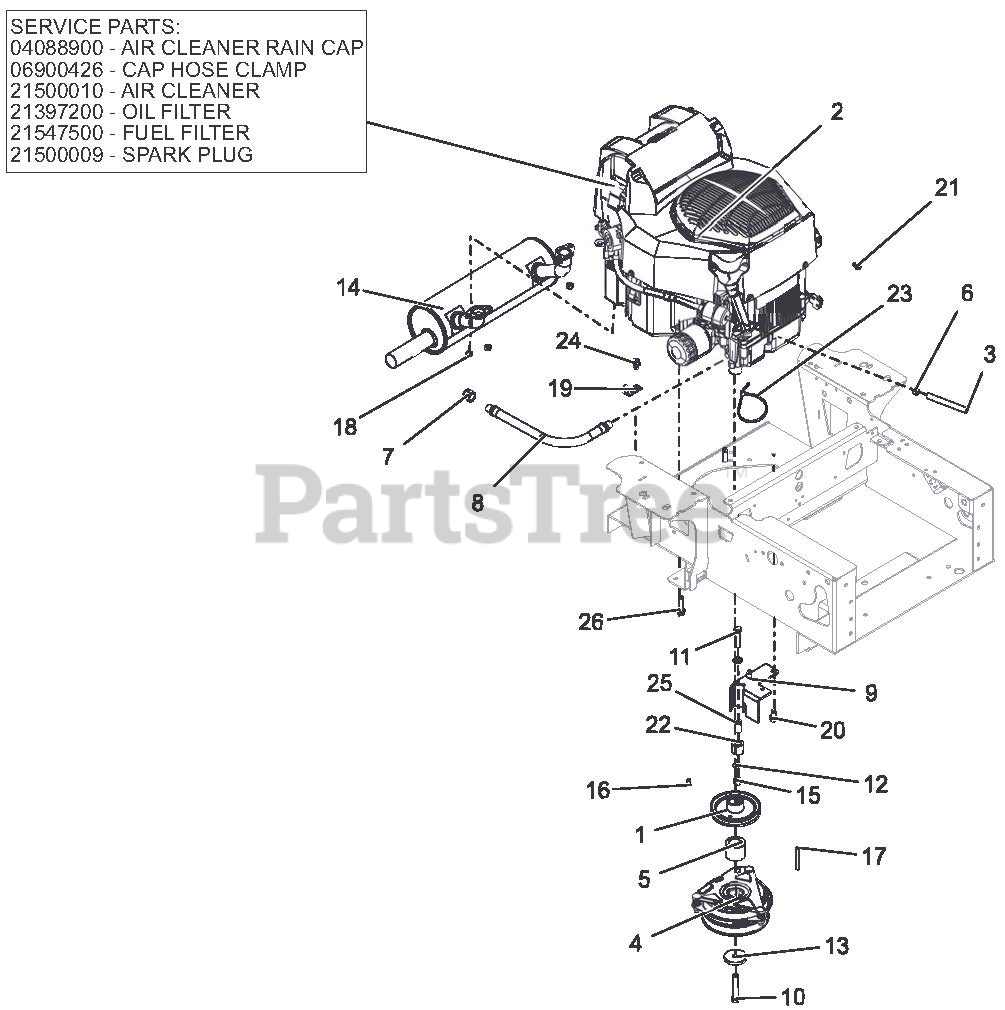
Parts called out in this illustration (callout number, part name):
1	PULLEY, 4.50 OD X 1.127 ENGINE - BLACK
2	ENGINE, KOHLER ZT730 CONFIDANT
2	AIR CLEANER RAIN CAP
2	CAP HOSE CLAMP
2	AIR CLEANER
2	OIL FILTER
2	FUEL FILTER
2	SPARK PLUG
3	.25 LOW-PERM GAS HOSE 7.50" VALVE TO ENGINE
4	CLUTCH, OGURA GT2.5-FE02
5	SPCR, 1.125 X 1.75 X 1.400
6	CLAMP, FUEL LINE
7	PIPE, CAP 3/8 NPT FEMALE
8	HOSE, HYD .38-11-OK M6N0-M6N0
9	BRKT, CLUTCH STOP
10	BLT-HEX .44-20 X 2.50 GR5 EP 80 YWZC
11	BLT-HEX .38-16 X 1.75 GR5 YWZC
12	WSHR-FL-STL .406 X .812 X .065 YWZ
13	WSHR-FL-STL .469 X 2.00 X .25 YWZC
14	MUFFLER, KOHLER CONFIDANT
15	NUT, LK-TOP-FLG .38-16 YWZC
16	KEY-SQ .250 X .250 X .625
17	KEY, .25 X .25 X 2.25
18	NUT-LK-TOP M8-1.25 YWZC
20	SCR-TAP .38-16 X .75 HWH TR YWZ
21	SCR-TAP .38-16 X .50 HWH TR YWZ
22	BUMPER, RUBBER .62 X 1.0 X .88 LG
23	CABLE, TIE 5.50 LG
24	SCR-TAP .38-16 X .50 HWH TR YWZ
25	BUSH., S .391 X .622 X .95 ST REV A
26	SCR-TAP .38-16 X 1.50 HWH TR YZ
